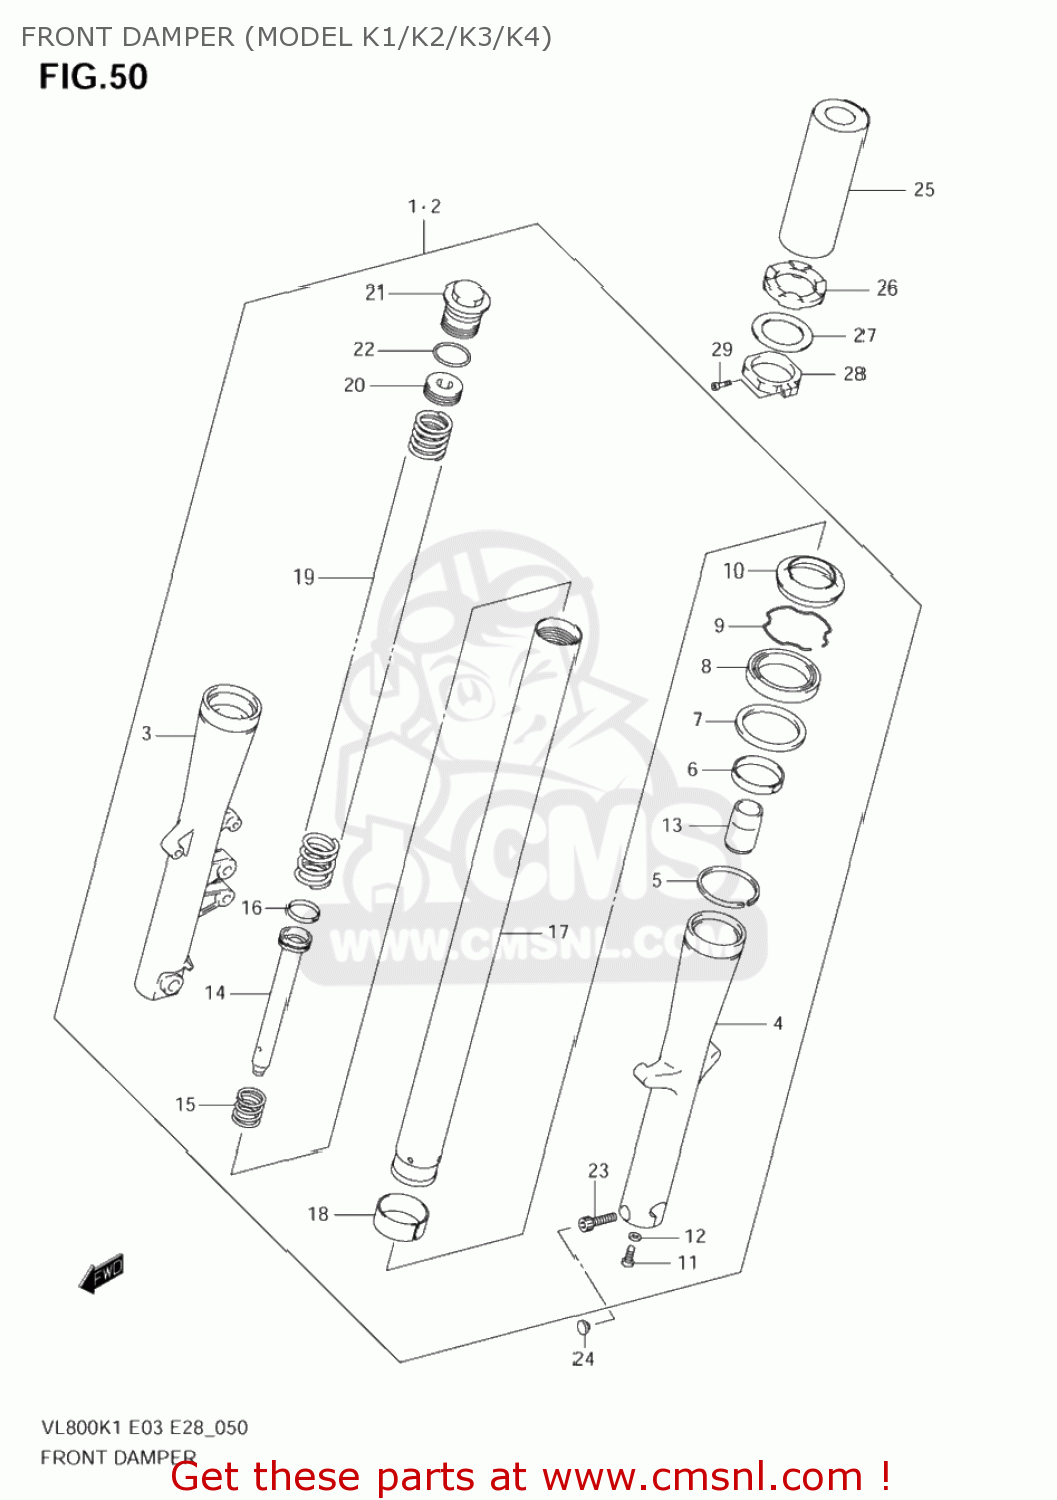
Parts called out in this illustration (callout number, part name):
1	DAMPER ASSY,FR FORK,R
2	DAMPER ASSY,FR FORK,L
3	TUBE,OUTER,R
4	TUBE,OUTER,L
5	GUIDE,CASE
6	BUSH,GUIDE
7	SPACER,SEAL
8	SEAL,OIL
9	CIRCLIP,FORK OIL SEAL
10	SEAL,DUST
11	BOLT,CENTER (8X18)
12	GASKET (NAS)
13	PIECE,OIL LOCK
14	SEAT,PIPE
15	SPRING,REBOUND
16	RING,PISTON
17	TUBE,INNER
18	BUSHING,SLIDE
19	SPRING,FR
20	BOLT,FORK INNER
21	BOLT,FORK
22	O RING
23	BOLT
24	CAP(OD:12)
25	CASE,UNDER
26	SEAT,RUBBER
27	WASHER
28	SPACER
29	BOLT
